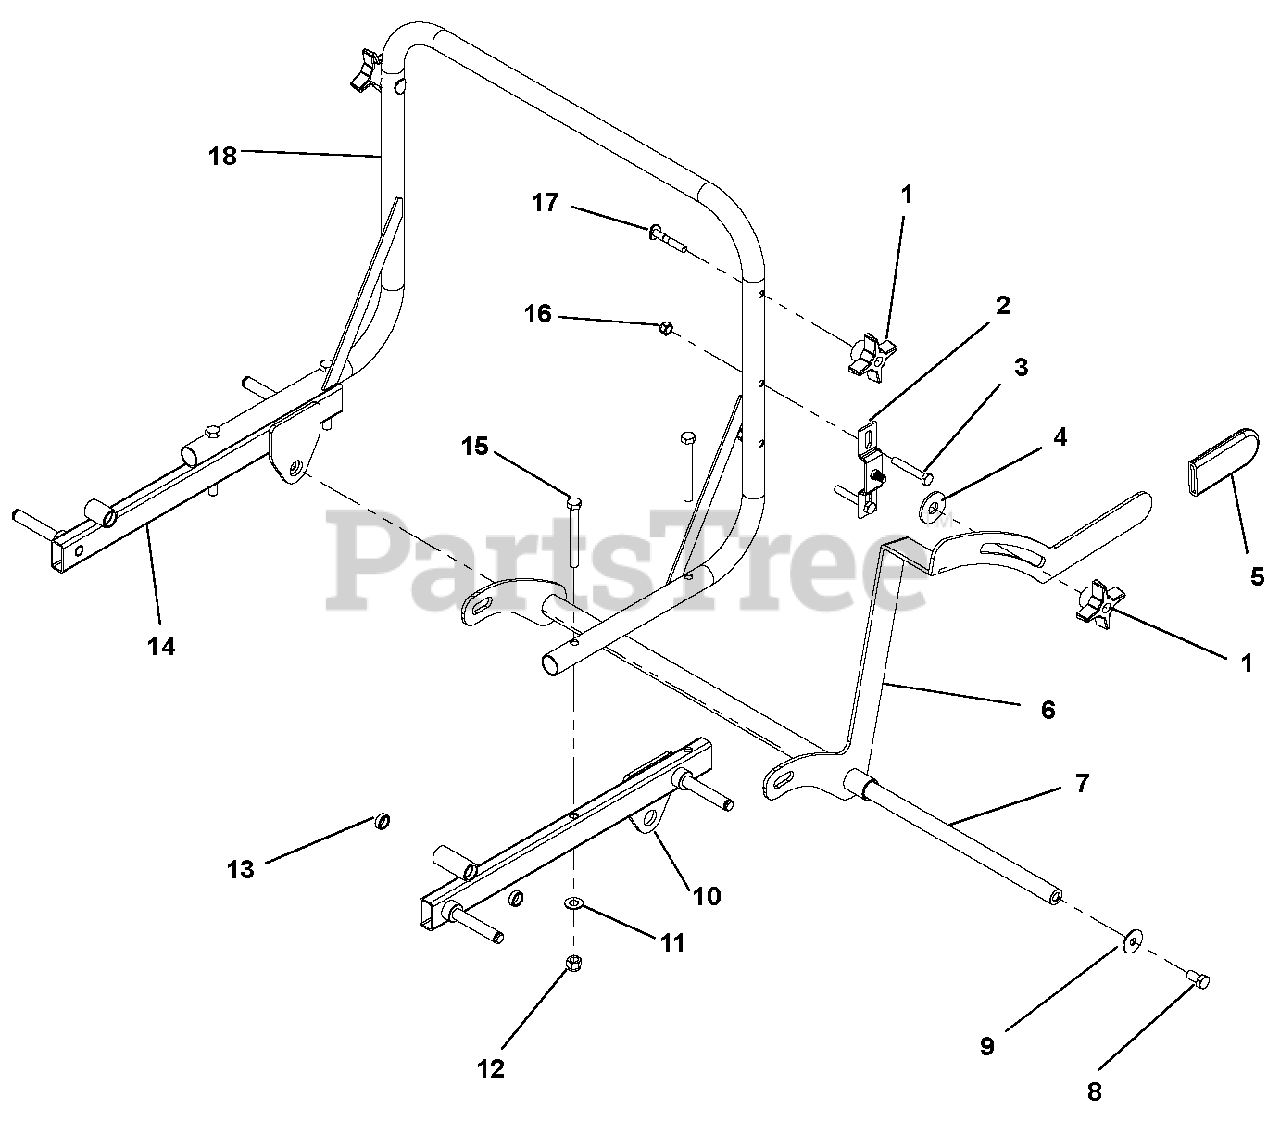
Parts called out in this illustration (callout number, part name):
1	Knob, 5/16 Thread
2	APV Height Adjust Bracket
3	Bolt, Hex .31-18 X 2.00
4	Washer, Flat .50 X 1.37 X .10
5	Grip (Flat Handle)
6	APV Height Adjustment Lever Weldment Assembly
7	APV Bar, Height Adjust Lever 21.90625"
8	Bolt, Hex .38-16 X .75
9	Washer, Flat, Steel .375 X 1.125 X .065
10	APV Side Rail Weldment Assembly, Left
11	Washer, Flat, Steel .406 X .812 X .065
12	Nut, Locking, Nylon .38-16
13	Oilite Sleeve AA-618-16
14	APV Side Rail Weldment Assembly, Right
15	Bolt, Hex .38-16 X 3.25
16	Nut, Locking, Nylon .312-18
17	Bolt, Cont. Head 5/16 X 2.00
18	APV Lower Handle Weldment
